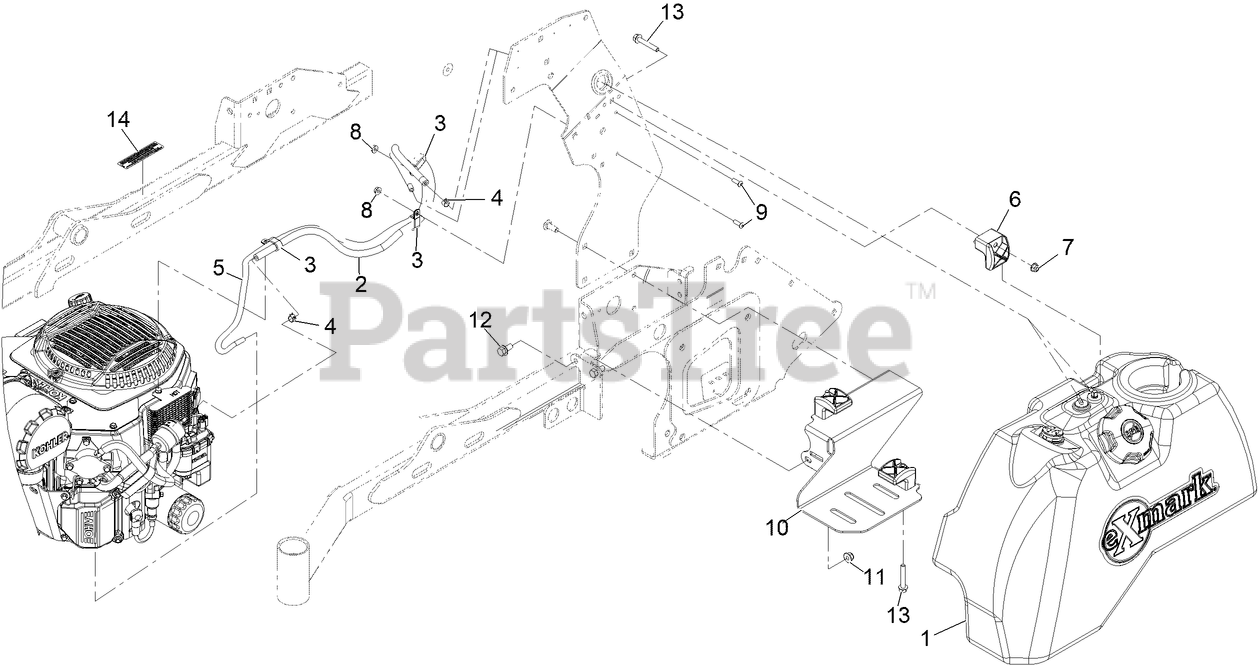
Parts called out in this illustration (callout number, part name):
1	ASM, FUEL TANK 8 GAL
2	HOSE-FUEL
3	CLAMP-R, DOUBLE TUBE
4	CLAMP-HOSE
5	HOSE-EMISSIONS
7	NUT-HF, NI
9	SCREW-HSBH
10	Bracket-Fuel Tank
11	NUT-HF, NI
12	Screw-HH Flg 3/8-16 X 3/4
13	SCREW-HHF
14	DECAL-ARRESTOR, SPARK
